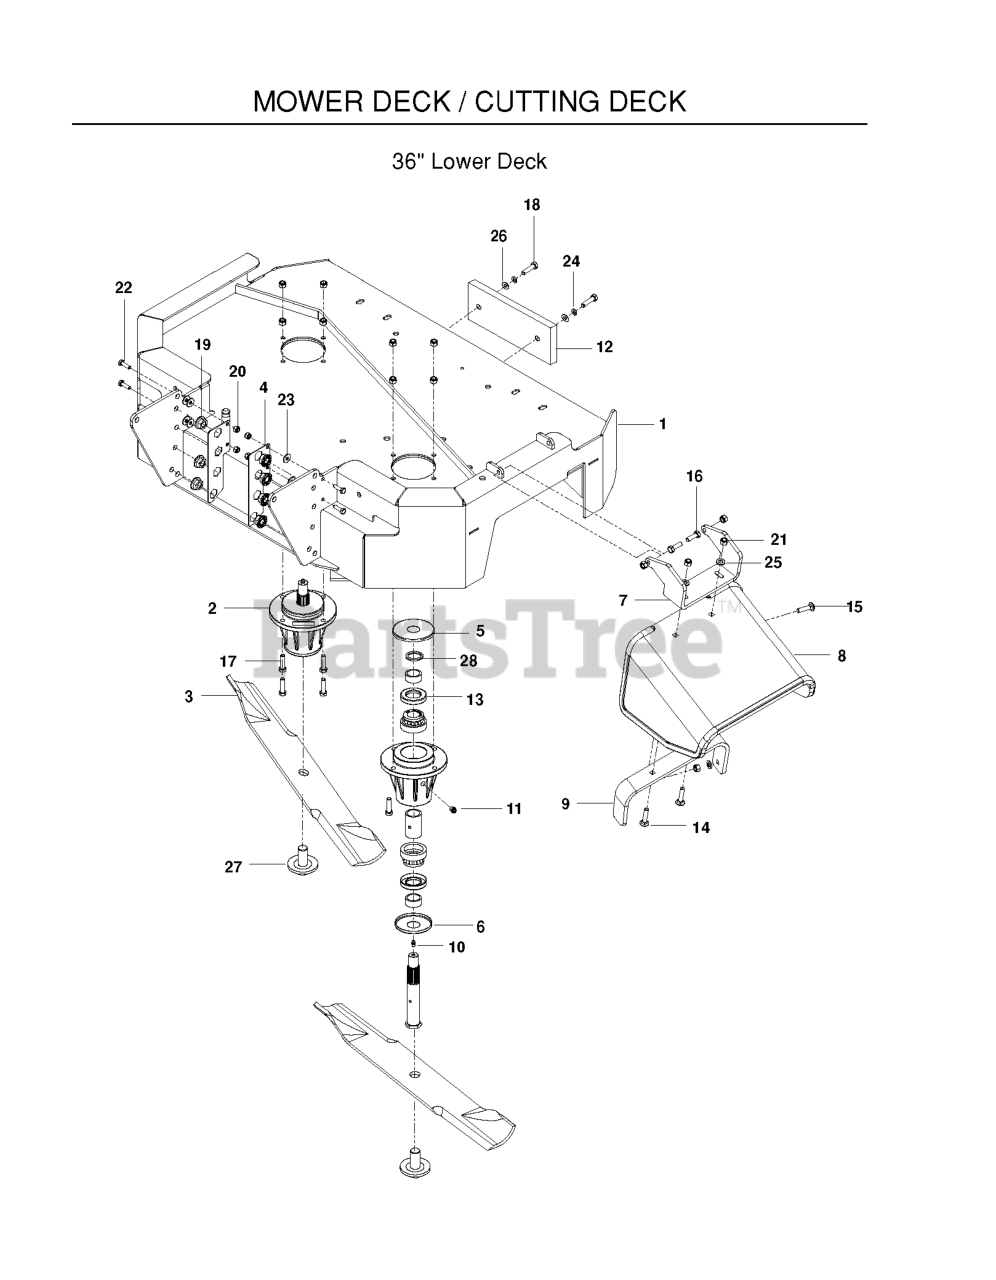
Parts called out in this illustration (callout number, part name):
1	DECK SVC WH3615 W/DECALS
2	HOUSING ASM, 72
3	BLADE OEM 18"
4	PLATE NUT - PAINTED
5	TOP DUST CAP
6	BOTTOM DUST CAP
7	HINGE CHUTE - BLACK
8	CHUTE, RUBBER DISCHARGE WB
9	BRKT, REINF-CHUTE WB
10	ZERK
11	PLUG-VENTED
12	WEIGHT, COUNTER, ORANGE
13	SHAFT SEAL
14	RHSNB 5/16-18 X 1-1/2 GR 5 ZD
15	BOLT, CARRIAGE 5/16X1-1/4
16	HCS 5/16C X 1
17	HCS 5/16C X 1 1/4
18	HCS 1/2-13 X 1-1/2 GR 5 ZD
19	NUT FLANGE 1/2-13 GR 5
20	NUT.1/4-20.HEX.NYLOC.ZD
21	NUT 5/16 NYLOC
22	HCS 1/4-20X7/8 GR5
23	WASHER 1/4 FLAT
24	WASHER 1/2" SPLIT LOCK
25	FLAT WASHER 5/16 SAE
26	WASHER 1/2" FLAT
27	BLADE BOLT/WASHER
28	MACHINE BUSHING
